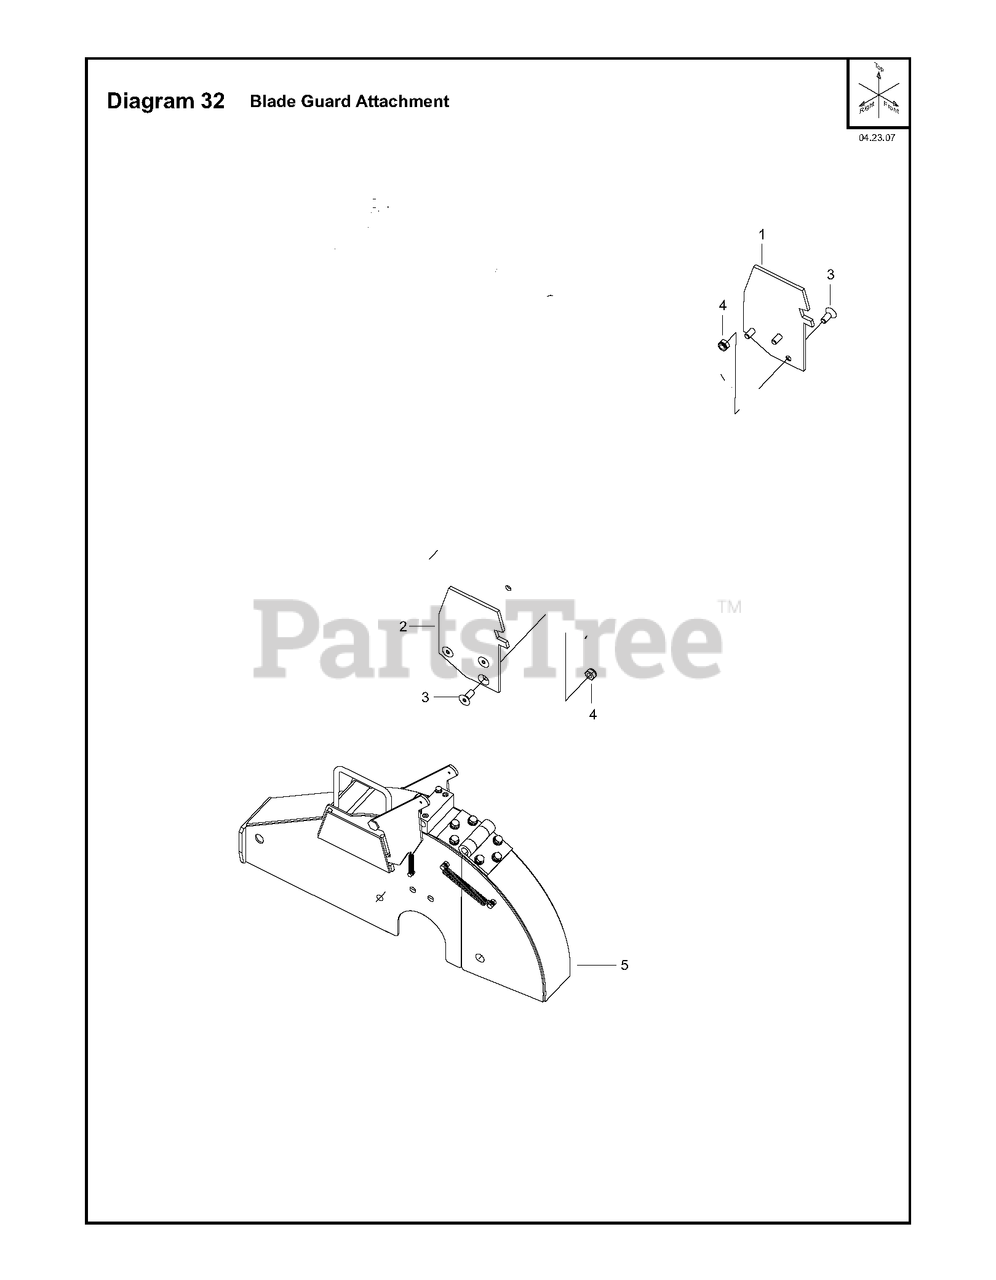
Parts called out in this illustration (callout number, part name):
1	LH SLIP ON SPADE- BLACK
2	BAIL.CONTROL.DR.21.ASM
3	SHCS. CSK M10 x 1.5 x 25mm
4	LOCKNUT. FIBER M10 DIN 985
